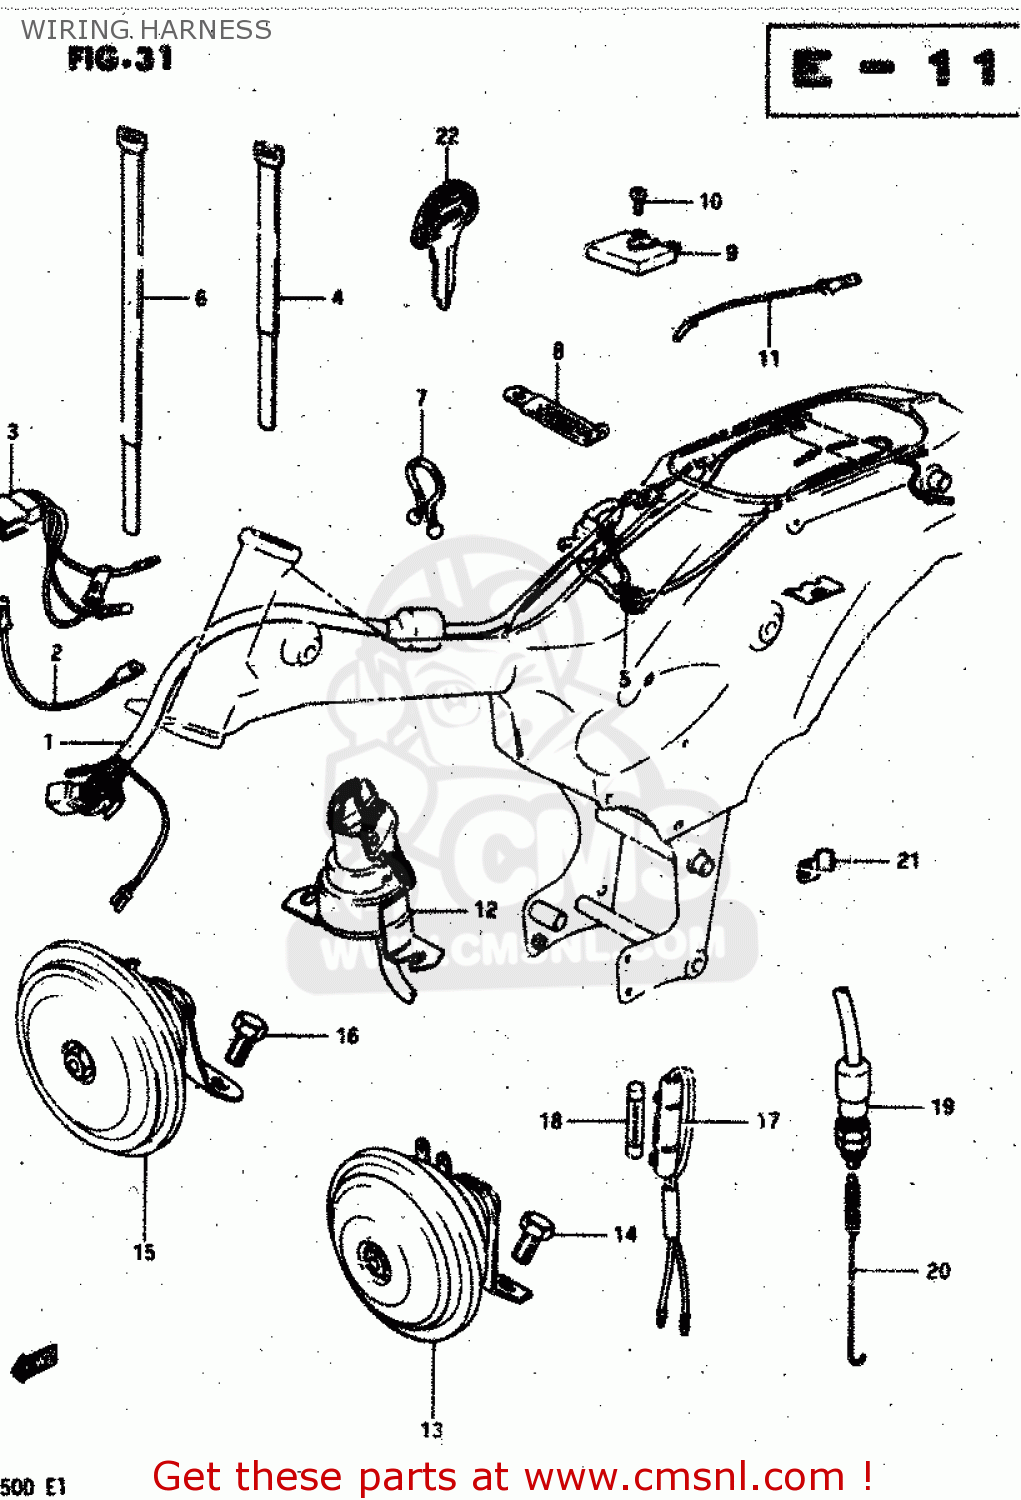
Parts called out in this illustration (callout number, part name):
1	WIRING HARNESS
2	WIRE,WIRING HARNESS LEAD
3	WIRE,HEADLAMP GROUND
4	CLAMP(L:250)
5	GROMMET
6	CLAMP
7	CLIP(ID:11.5)
8	CLAMP
9	RECTIFIER ASSEMBLY
10	SCREW 5X20
11	LEAD WIRE, RECTIFIER
12	SWITCH ASSY, IGNITION
13	HORN ASSY
14	BOLT(6X6)
15	HORN ASSY
16	BOLT(6X6)
17	BOX ASSEMBLY,FUSE
18	FUSE(15A)
19	SWITCH,BRAKE LAMP
20	SPRING
21	CLAMP
22	KEY,BLANK
